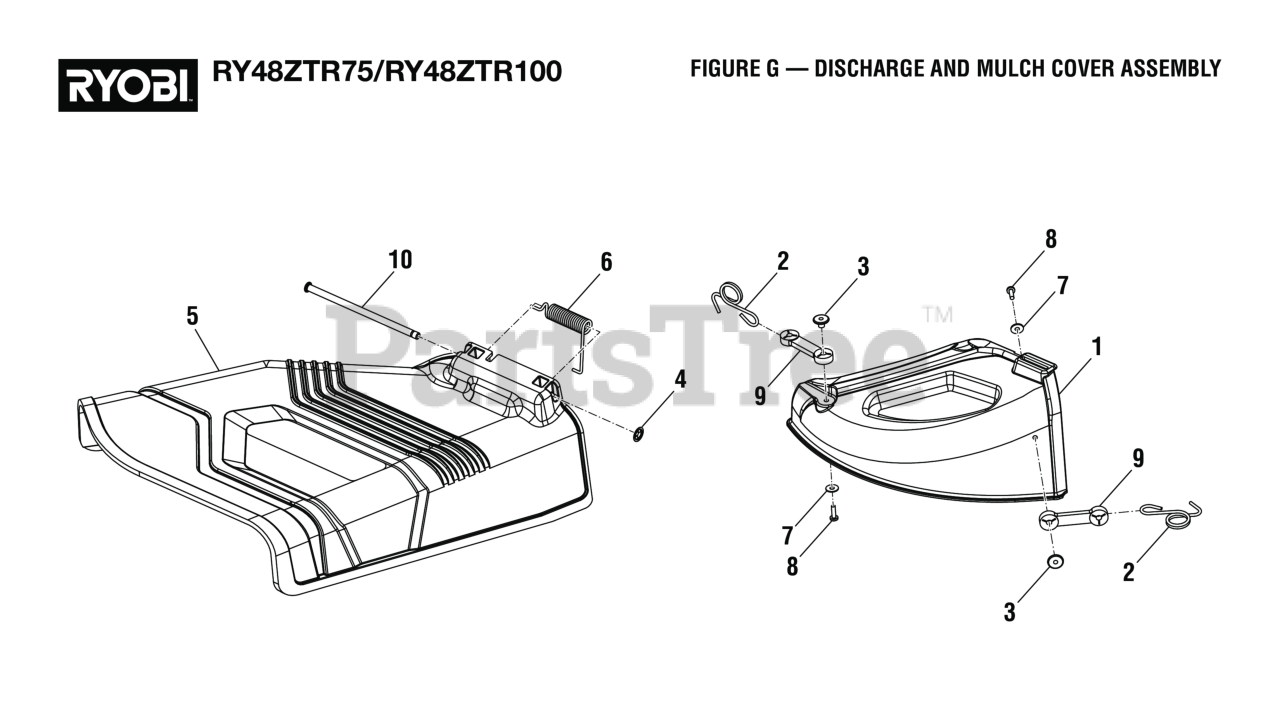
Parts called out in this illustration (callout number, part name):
1	Mulch Plug, ZTR
2	SPRING, LATCH
3	ANCHOR, BUNGIE, RIDING MOWER
4	Retainer Clip
5	Side Discharge Chute, 42 in. Deck
6	Torsion Spring (19 x 62 x 3.02t)
7	WASHER, FLAT, 5.3 X 15 X 1, STEEL,
8	SCREW,PPHMS, M5 X 0.8 X 16 - STEEL,
9	RUBBER STRAP, MULCHING COVER
10	Hinge Pin (7.85 x 175.85)
